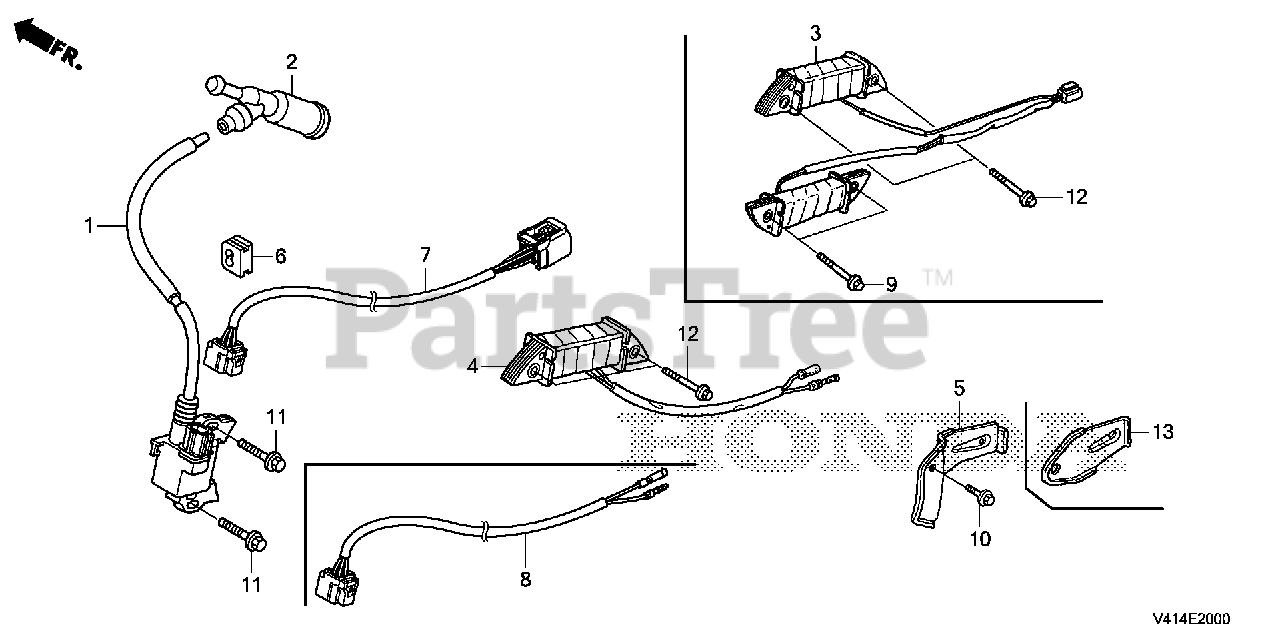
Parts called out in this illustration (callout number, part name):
1	COIL ASSY., IGNITION
2	CAP ASSY., NOISE SUPPRESSOR (NGK Y-EZD)
4	COIL ASSY., LAMP (12V/15W)
5	CLAMP, WIRE
6	GROMMET, WIRE
8	WIRE HARNESS ASSY., ENGINE
10	BOLT, FLANGE (6X12) (CT200)
11	BOLT, FLANGE (6X28) (CT200)
12	BOLT, FLANGE (6X32) (CT200)
